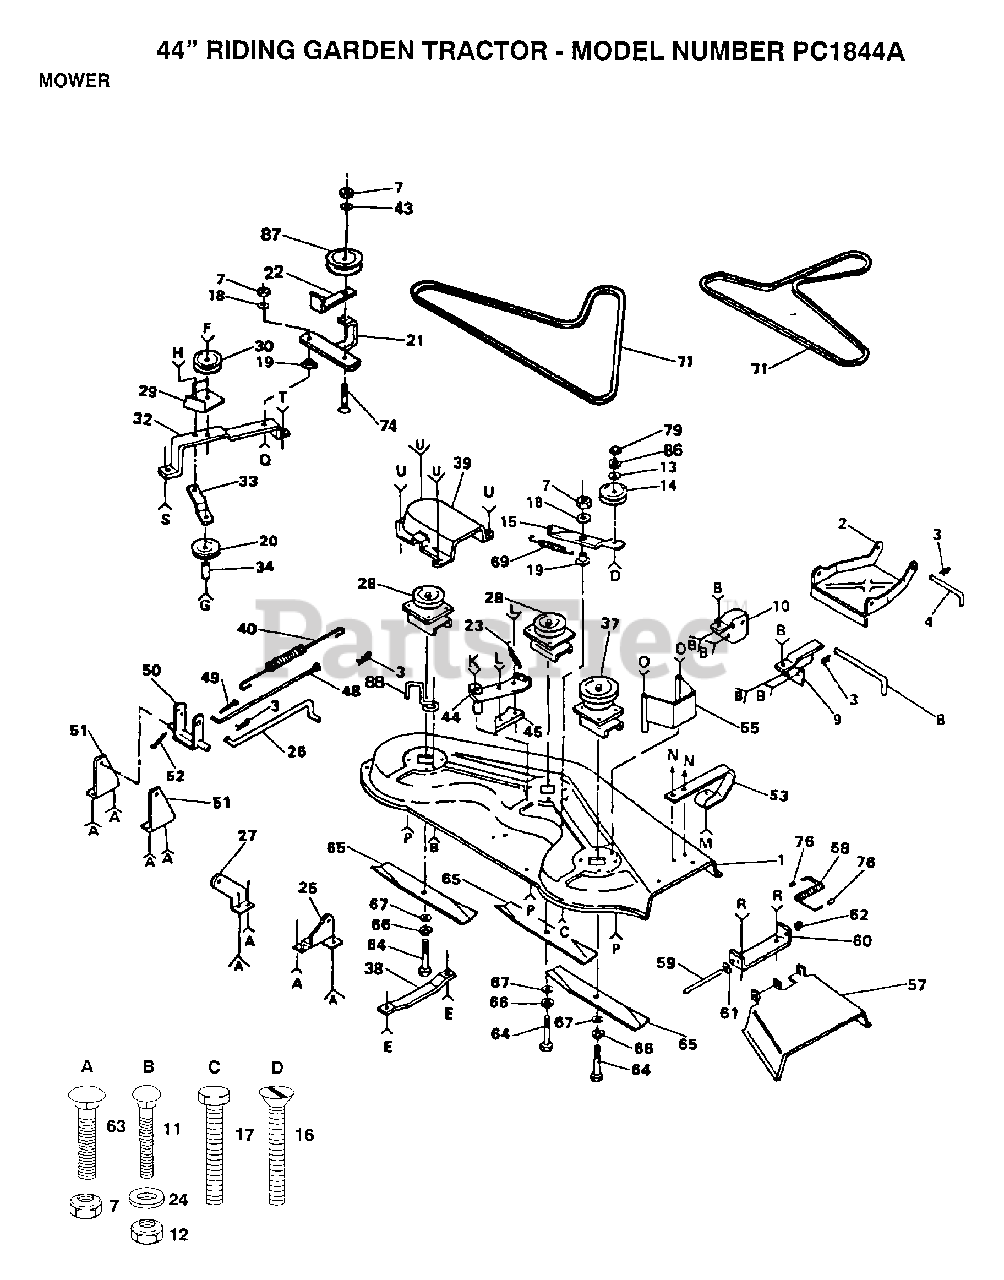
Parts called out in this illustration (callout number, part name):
2	LINK.PARALLEL
3	SPRING.RETAINER
4	"ROD, FRT. PARAL T"
5	LINK STOP
8	HINGE PIN T
9	BRACKET RH YT
10	BRACKET LH YT
11	BOLT
13	WASHER
14	IDLER.FLAT.GTV
15	ARM-IDLER YT
16	SCREW YT
18	"WASHER, WEAR LT"
19	SPACER RETAINER
20	IDLER-FLAT T
22	GUIDE BELT
23	SPRING-EXT YT
24	WASHER M
25	BRKT SUSP REAR RH
27	BRKT SUSP REAR LH
29	GUIDE-BELT YT
30	IDLER-INSIDE T
32	"SUPPORT YT, BAR"
33	BRACE-IDLER YT
34	SPACER
35	BOLT - HEX 3/8 - 16 X 3
38	RUNNER-LH M
39	GUARD YT
41	BOLT SHOULDER
42	LOCKNUT
43	WASHER
44	BRAKE ARM LT
45	BRAKE-BLOCK YTV
46	WASHER
48	ROD BRAKE YT
51	SUPPORT SHAFT YT
55	ASSY RH BELT GRD
56	BOLT
57	DEFLECTOR SHIELD
59	ROD-HINGE T
61	WASHER
62	NUT PUSH M
63	BOLT
64	BOLT.3/8-24X1-1/2
67	WASHER
68	SCREW
70	BOLT
71	BELT-V.79.1.MWR
74	BOLT
76	CAP-SLEEVE LT
77	BOLT
79	NUT.HEX.3/8-16UNC
80	NUT.HEX.5/16-18
81	LOCKWASHER
83	BOLT
86	LOCKWASHER
87	PULLEY IDLER
88	BELT RETIANER
89	WASHER
